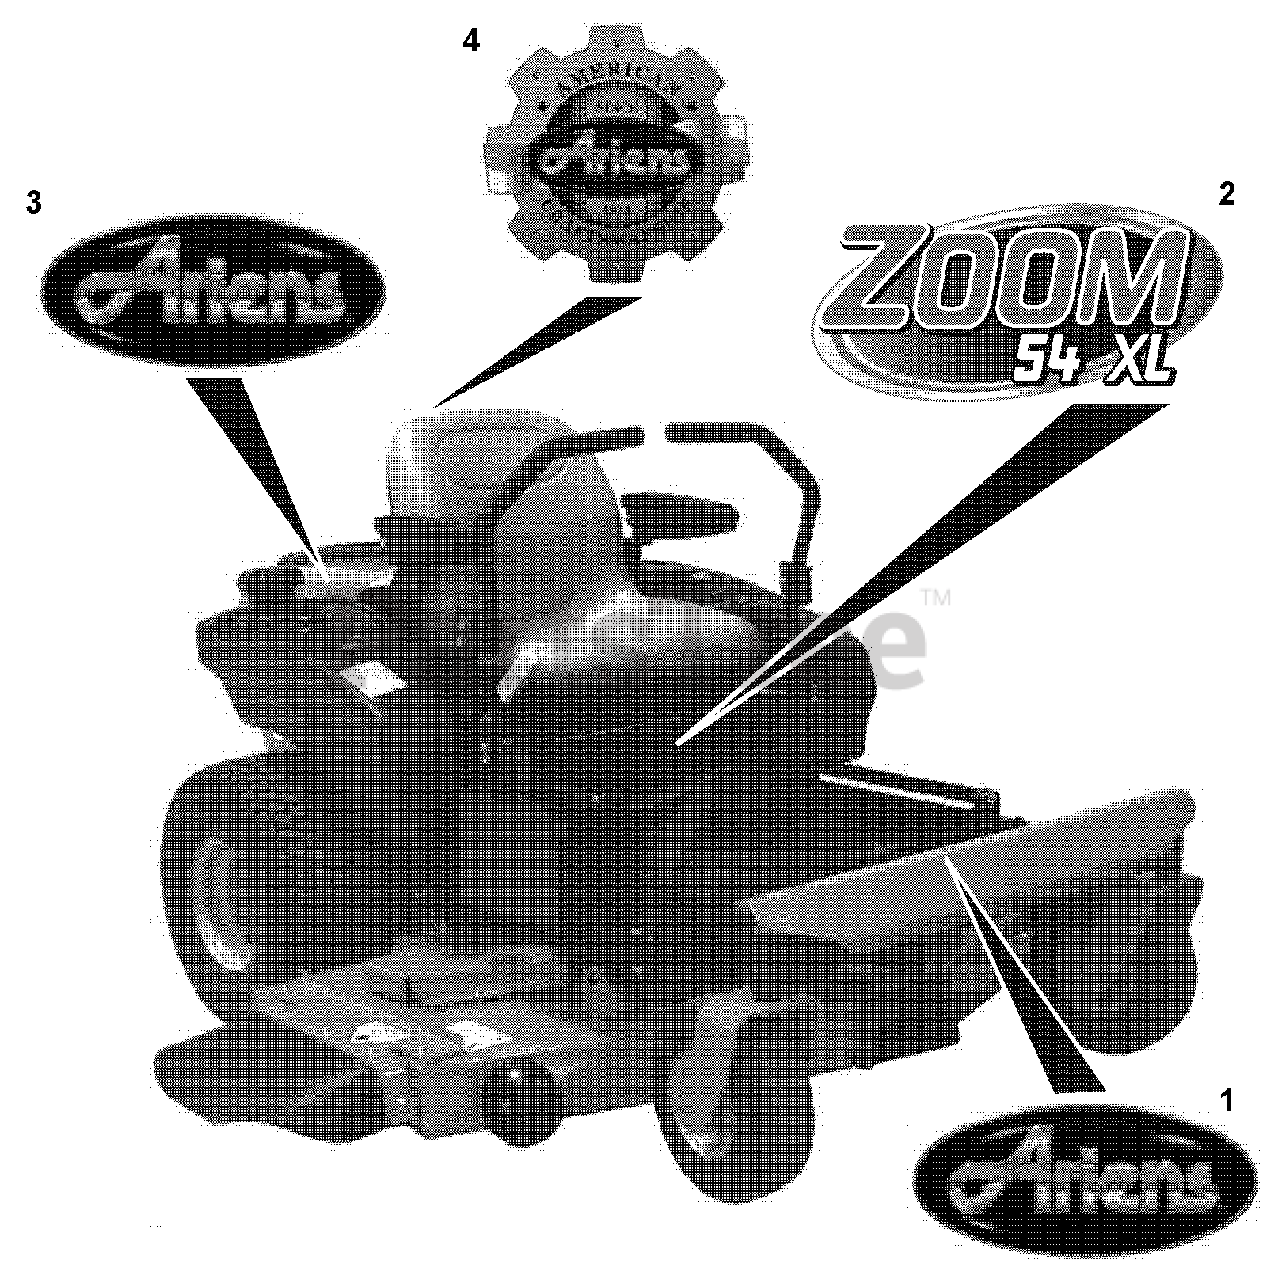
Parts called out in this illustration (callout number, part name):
1	DECAL, ARIENS JEWEL
2	DECAL,ZOOM 42 XL
2	DECAL, ZOOM 48 XL
2	DECAL, ZOOM 54 XL
3	DECAL, ARIENS JEWEL
4	Decal, Ariens American Heritage
